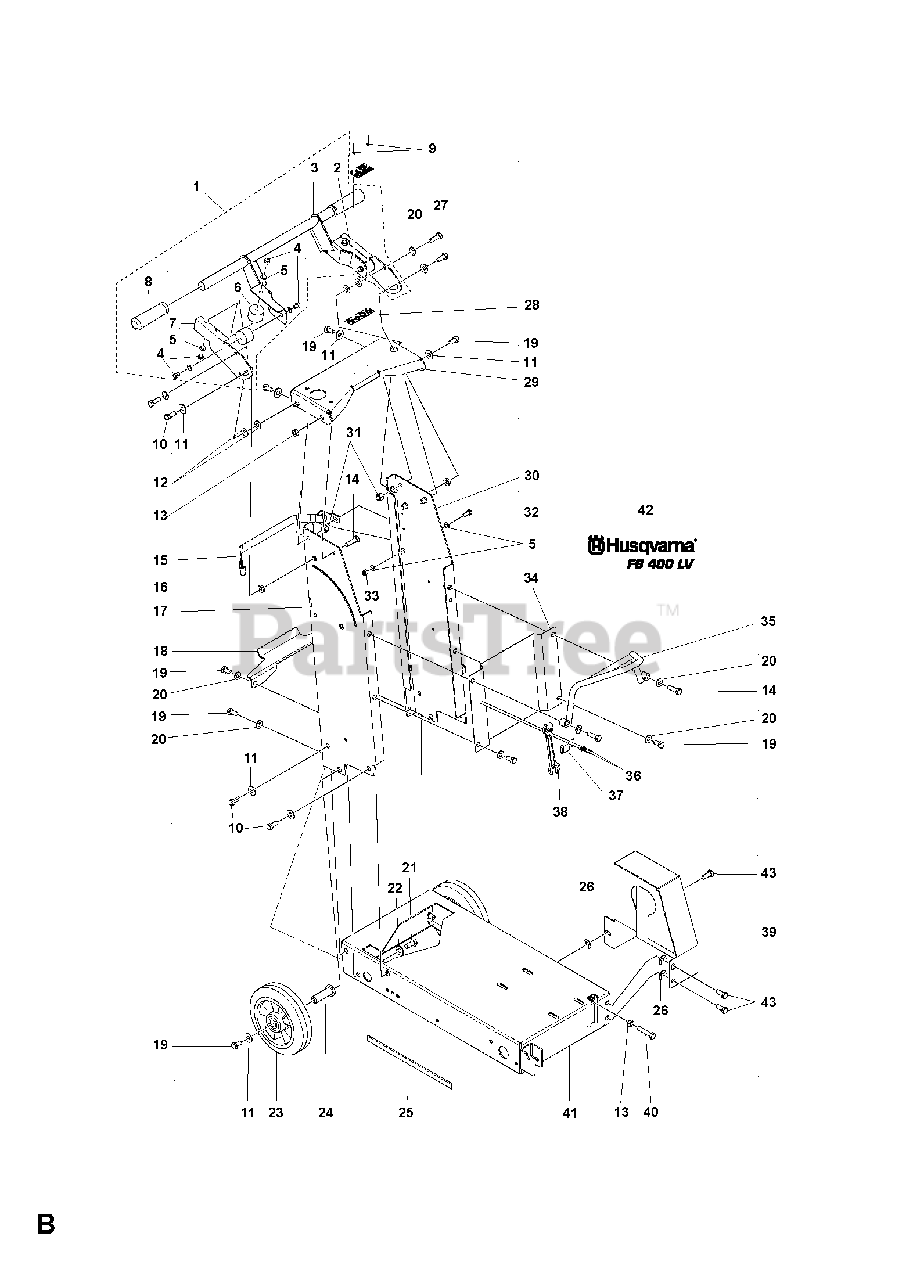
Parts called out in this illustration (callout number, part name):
5	WASHER
6	ANTIVIBRATION ELEMENT
20	WASHER
22	WASHER
31	HEXAGON LOCKING NUT
